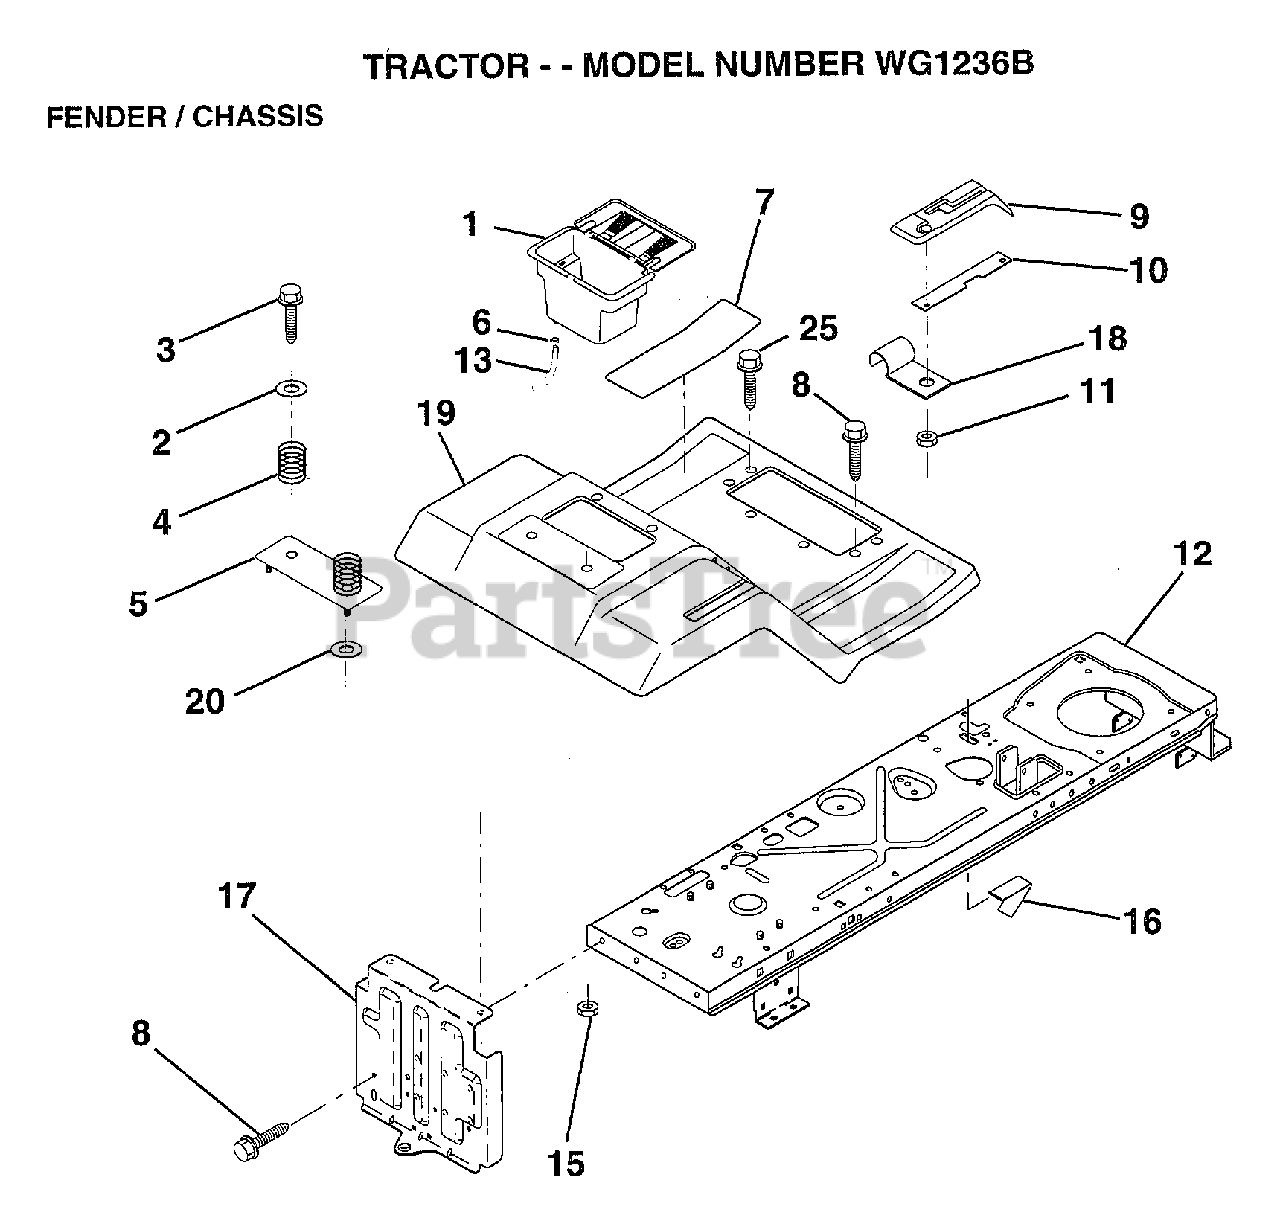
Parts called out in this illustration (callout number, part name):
2	WASHER
3	SCREW
4	SPRING COMPRESSIO
5	PLATE.FEND.LR.ASM
6	HOSE CLAMP T
7	PAD FOOTREST
8	SCREW
10	PLATE LOCK SHIFT
11	NUT
12	CHASSIS.WELD.ASM.
13	TUBE T
14	NUT
15	NUT HXKEP 1/4X20
17	DRAWBAR ASM LR
18	"CLIP,INSULATOR"
19	FENDER/FOOTREST
25	SCREW
